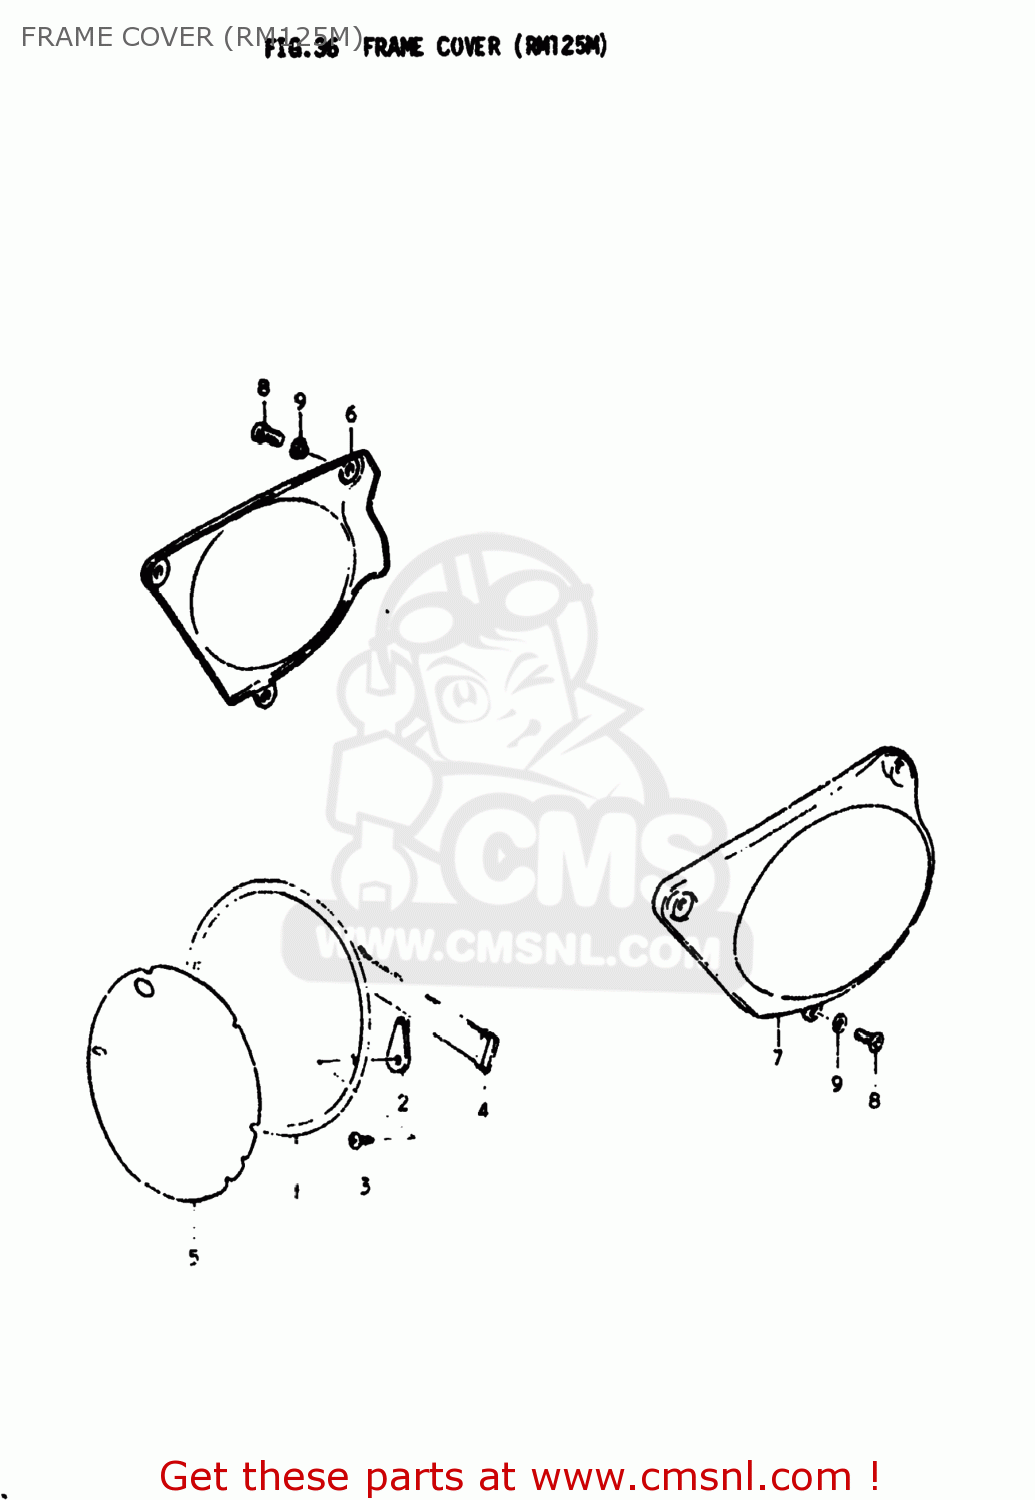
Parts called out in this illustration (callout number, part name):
1	PLATE SET,FRONT
3	SCREW 6X12
4	BAND
5	EMBLEM,FRONT NUMBER PLATE
6	COVER,FRAME,RIGHT
7	COVER,FRAME,LEFT
8	SCREW 6X12
9	WASHER
